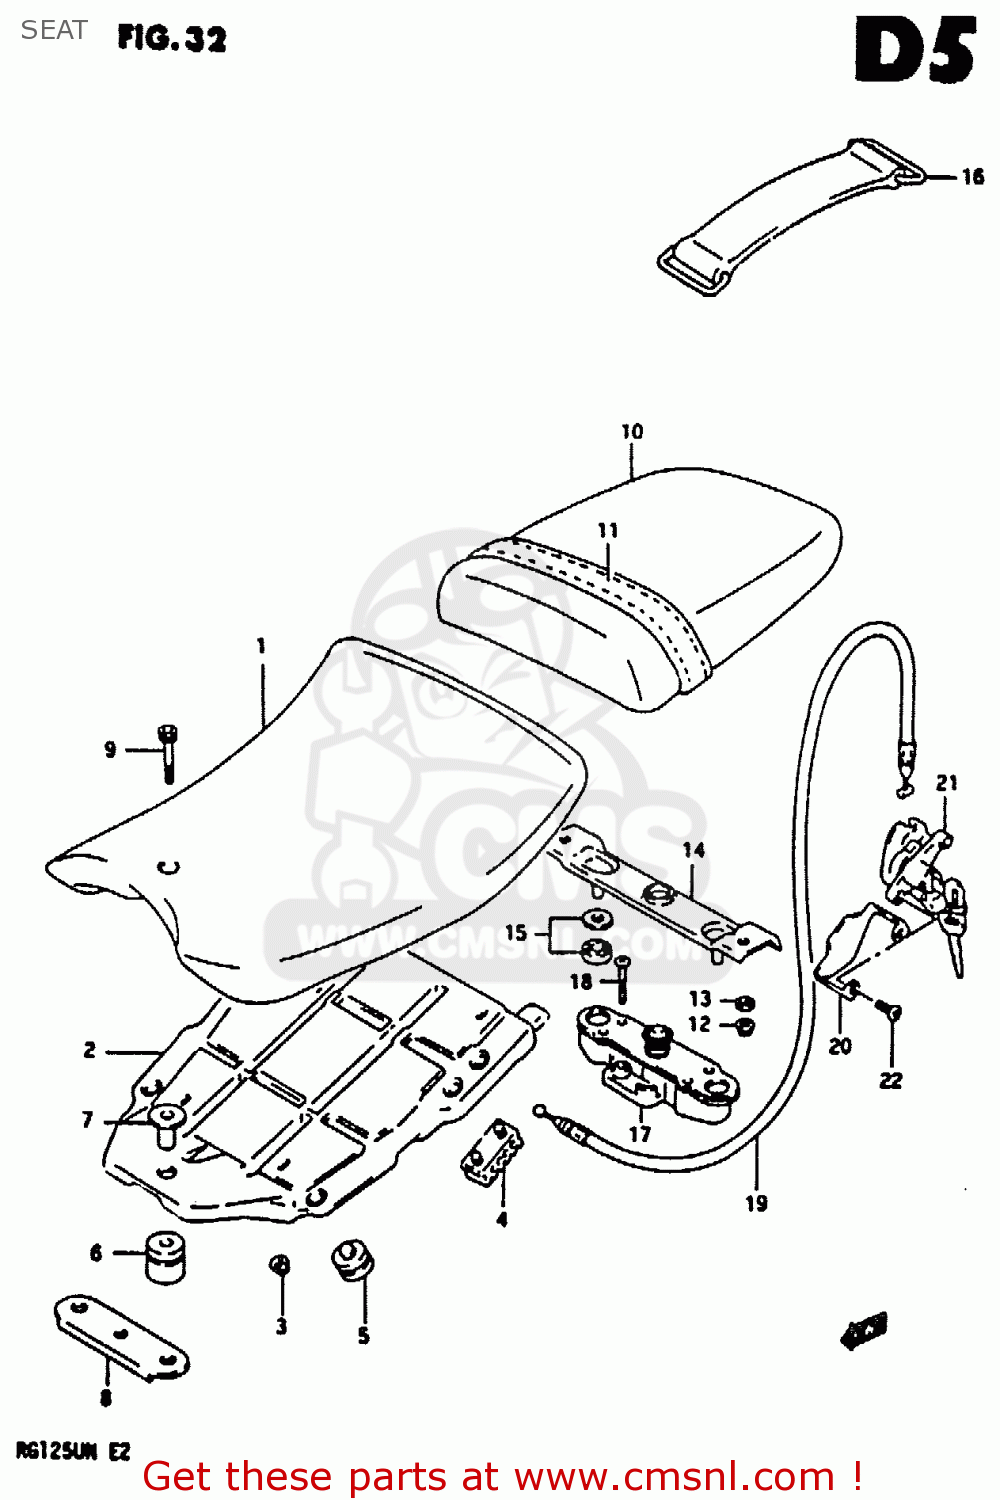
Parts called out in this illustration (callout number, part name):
1	SEAT ASSY (BLACK)
2	FRAME, SEAT BOTTOM
3	NUT
4	CUSHION,SIDE
5	CUSHION
6	CUSHION,SEAT
7	COLLAR,FR
8	PLATE,SEAT FR
9	BOLT
10	SEAT ASSY, PILLION (BLACK)
11	BAND, SEAT (BLACK)
12	NUT
13	WASHER
14	STRIKER,SEAT LOCK
15	CUSHION
16	BAND
17	LOCK ASSY,SEAT STRIKER
18	SCREW,6X30
19	CABLE,SEAT LOCK CABLE
20	PLATE,SEAT LOCK GUARD
21	LOCK SET,SEAT & HELMET
22	SCREW
